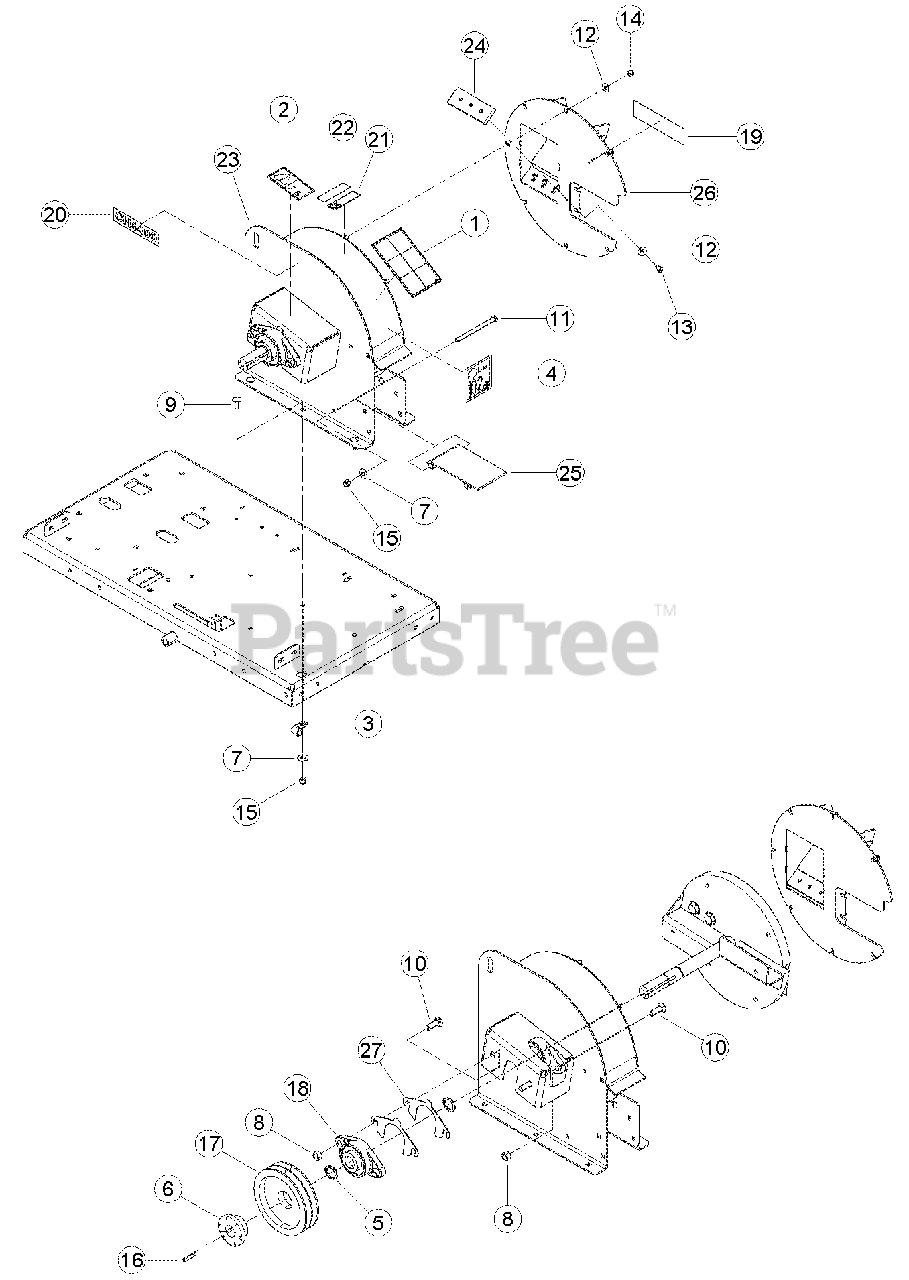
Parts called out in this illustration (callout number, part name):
1	DECAL, OPERATING INSTRUCTIONS ISO
2	DECAL, MAINTENANCE ISO
3	CLAMP, 9/16" COATED
4	DECAL, 107 DB (CE COMPLIANT ONLY)
5	SNAP RING, 1-1/4 EXT. HEAVY DUTY
6	BUSHING, SDS 1-1/4"
7	WASHER, 3/8 FLAT ZP
8	NUT, 1/2 CENTERLOCK GRB ZP
9	BOLT, 3/8 X 1 CRG GR5 NC ZP
10	BOLT, 1/2 X 1-1/2 CRG GR5 ZP
11	BOLT, 3/8 X 5 HEX HD GR5 ZP
12	WASHER, 5/16 FLAT ZP
13	BOLT, 5/16 X 5/8 HEX HD GR5 ZP
14	NUT, 5/16 NE NYLOCK ZP
15	NUT, 3/8 NE NYLOCK ZP
16	KEY, 1/4 SQUARE X 1-1/2 LONG PLAIN
17	SHEAVE, 2B 6.6 SDS
18	BEARING, 1-1/4" DIA 2 BOLT FLANGE
19	DECAL, ECHO BEARCAT 6.82 X 1.90
20	DECAL, MODEL CH4400
21	DECAL, INFORMATION (CE COMPLIANT ONLY)
22	DECAL, ATLANTIC BRIDGE LTD INFO (CE COMPLIANT ONLY)
23	WELDMENT, CHIPPER HOUSING
24	ANVIL, CHIPPER
25	WELDMENT, CHIP DEFLECTOR
26	WELDMENT, DISK COVER
27	SHIM, BEARING
